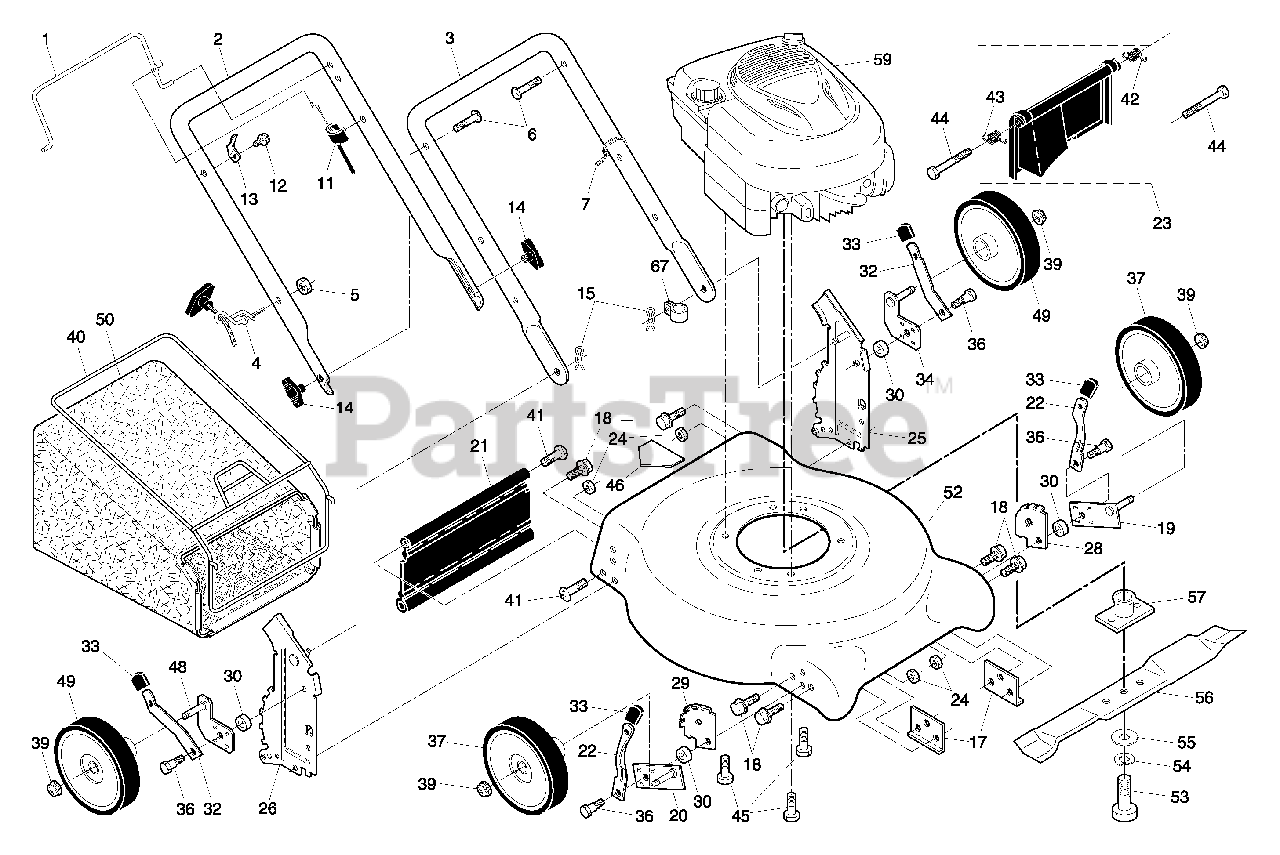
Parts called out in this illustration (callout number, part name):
1	Control Bar
2	Upper Handle
3	Lower Handle
4	Rope Guide
5	Nut, Hex 1/4-20
6	Handle Bolt
7	Wire Tie
11	Engine Zone Control Cable
12	Screw, Threaded, Rolled #10-24 x 1/2
13	Up-Stop Bracket
14	Handle Knob
15	Hairpin Cotter
17	Support Bracket
18	Screw 1/4-20 x 3/8
19	Axle Arm Assembly, Front, LH
20	Axle Arm Assembly, Front, RH
21	Rear Skirt
22	Selector Spring, Front
23	Kit, Rear Door
24	Locknut, Hex 5/16-18
25	Handle Bracket Assembly, LH
26	Handle Bracket Assembly, RH
28	Wheel Adjusting Bracket, Front, LH
29	Wheel Adjusting Bracket, Front, RH
30	Spacer
32	Selector Spring, Rear
33	Selector Knob
34	Axle Arm Assembly, Rear, LH
36	Shoulder Bolt 5/16-18
37	Wheel & Tire Assembly, Front
39	Nut, Hex, Flangelock 3/8-16
40	Frame, Grassbag
41	Hinge Screw
42	Spring, Rear Door, LH
43	Spring, Rear Door, RH
44	Bolt, Rear Door
45	Screw, Hex Head, Threaded, Rolled 3/8-16 x 1
46	Danger Decal
48	Axle Arm Assembly, Rear, RH
49	Wheel & Tire Assembly, Rear
50	Grassbag
52	Kit, Lawn Mower Housing
53	Screw, Hex Head, Grade 8, 3/8-24 x 1-3/8
54	Helical Lockwasher
55	Hardened Washer
56	21" Blade
57	Blade Adapter
67	Clip, Cable
